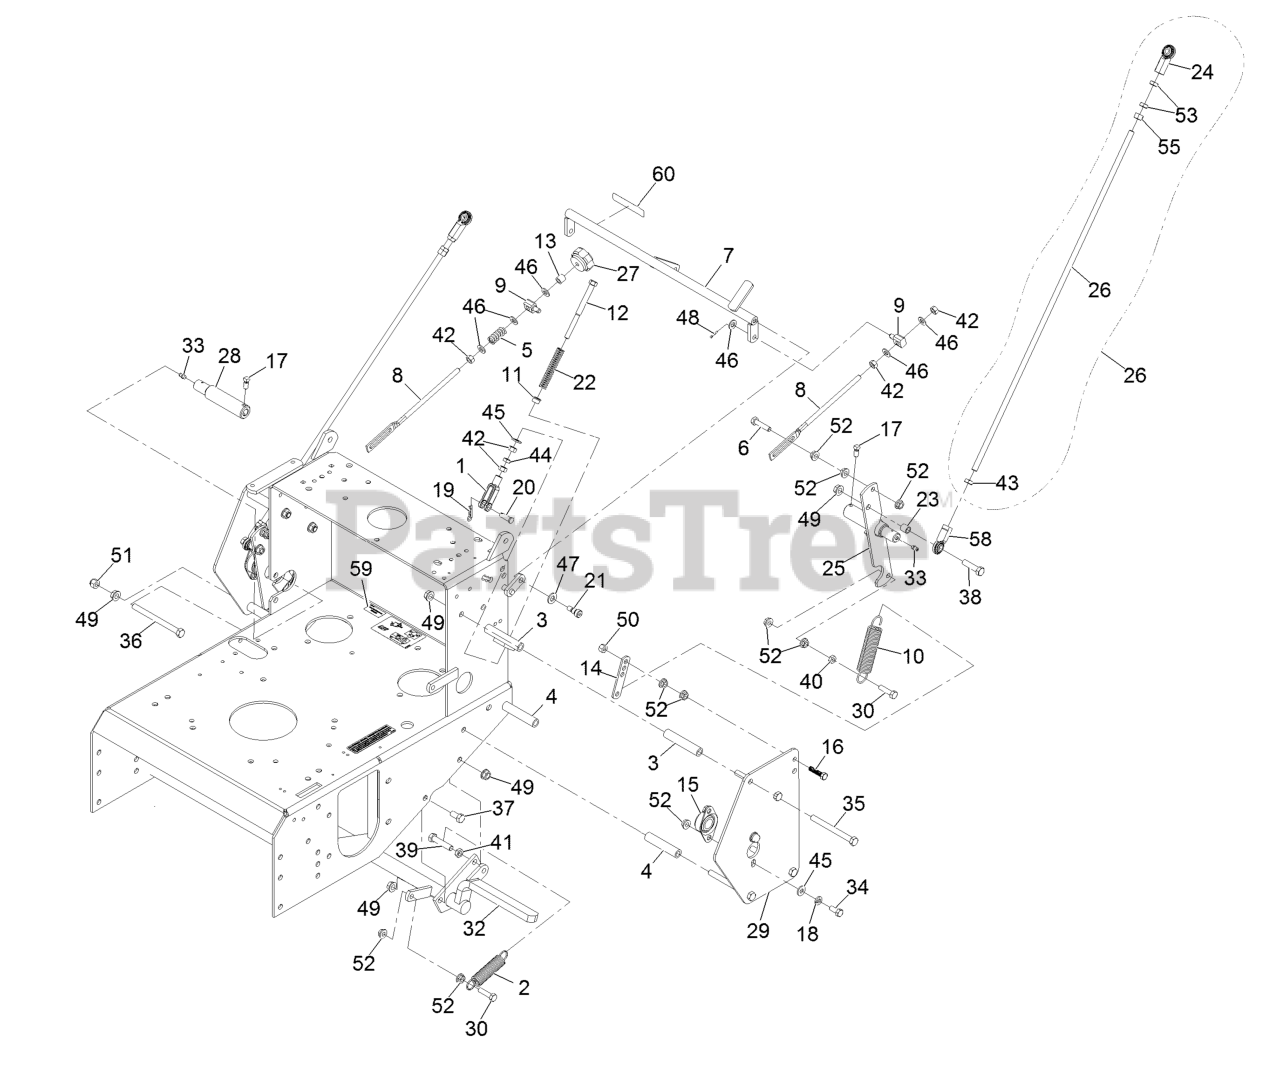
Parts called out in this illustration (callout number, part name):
1	Yoke-Adjustable
3	Spacer-Shield
4	Spacer-Shield
5	Spring-Compression
6	Screw-HH 5/16-18 X 1 3/8 Special
7	Crank-Control, Speed
8	Link-Control, Speed
9	Swivel-Adjustable, Short
11	Bushing-Flanged
12	Bolt-Neutral Return
14	Tab-Spring, Extension
15	Bearing-Flanged
16	Bolt-HH 5/16-18 X 1 1/4 Tap
17	Setscrew-5/16-18 X 5/8
18	Washer-Lock 5/16 Heavy
19	Hairpin-Cotter
20	Pin-Clevis 5/16 X 1 49/64
21	Screw-Sh 5/16-18 X 1 3/8
22	Spring, Neutral Return
23	Spacer-Tube, Pump Link
24	Balljoint
25	Shaft-Control, LH
26	Linkage, Drive
26	Drive Link ASM
27	Knob-Tracking
28	Shaft-Control, RH
29	Shield-Control
30	Screw,HH Special 5/16-18 X 1.25
32	Shaft-Cross, Brake
33	Zerk-1/4-28 Str
34	Screw-HH 5/16-18 X 3/4
35	Screw-HH 3/8-16 X 4
36	Screw-HH 3/8-16 X 4-1/2
37	Screw-HH 3/8-16 X 3/4
38	Screw-HH 3/8-16 X 1 1/2
39	Screw-HH 3/8-16 X 1 3/4
40	Nut-Jam 5/16-18
41	Nut-Jam 3/8-16
42	Nut-Hex 5/16-24
43	Nut-Jam 3/8-24 LH
44	Nut-Jam 5/16-24
45	Washer-1/4 Std
46	Washer-5/16 SAE
47	Washer-3/8 SAE
48	Pin-Cotter 3/32 X 1/2
49	Nut-Whizlock 3/8-16
50	Nut-Nyloc 5/16-18
51	Nut-Nyloc 3/8-16
52	Nut-Whizlock 5/16-18
53	Nut-Jam 3/8-24
55	Nut-Hex 3/8-24
58	Joint-Ball End
59	Decal-Patent
60	Decal-Tracking Adjustment
